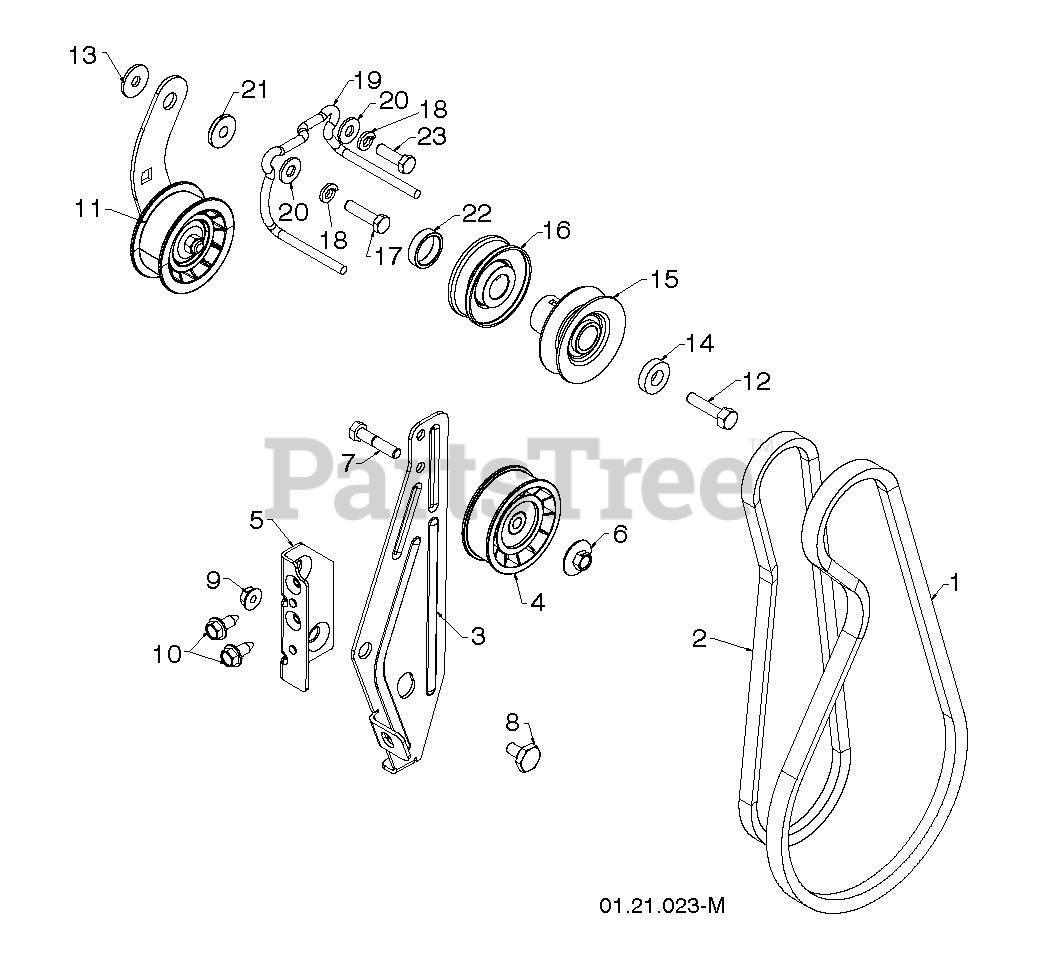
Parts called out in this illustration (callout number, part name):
1	BELT.V.IMPELLER
2	V-BELT.TRACTION.HYDRO.II.SNOW
3	ARM.IDLER BRAKE.CLEAR.ZINC
4	PULLEY.W/SPACER.2.75
5	BRACKET.IDLER.PIVOT.ZINC
6	NUT.FLANGE.HEX.5/16X18.BLACK
7	HEX BOLT
8	BOLT.SHOULDER.1/2X12
9	NUT.LOCK.5/16-18
10	BOLT.5/16HEX.WHS.HD
11	ARM.ASM.TRACTION.IDLER.
12	BOLT.BLADE
13	STEEL WASHER
14	WASHER, FLAT 3/8
15	PULLEY.IMPELER.
16	PULLEY,ENGINE TRACTION DRIVE
17	CAPSCREW.HEXHD.5/16X1.25.
18	LOCKWASHER
19	GUIDE.BELT.CHAIN.LS.SNOW
20	WASHER.20X8.5
21	BUSHING.BRAKE.ARM
22	SPACER.ENGINE.PULLEY
